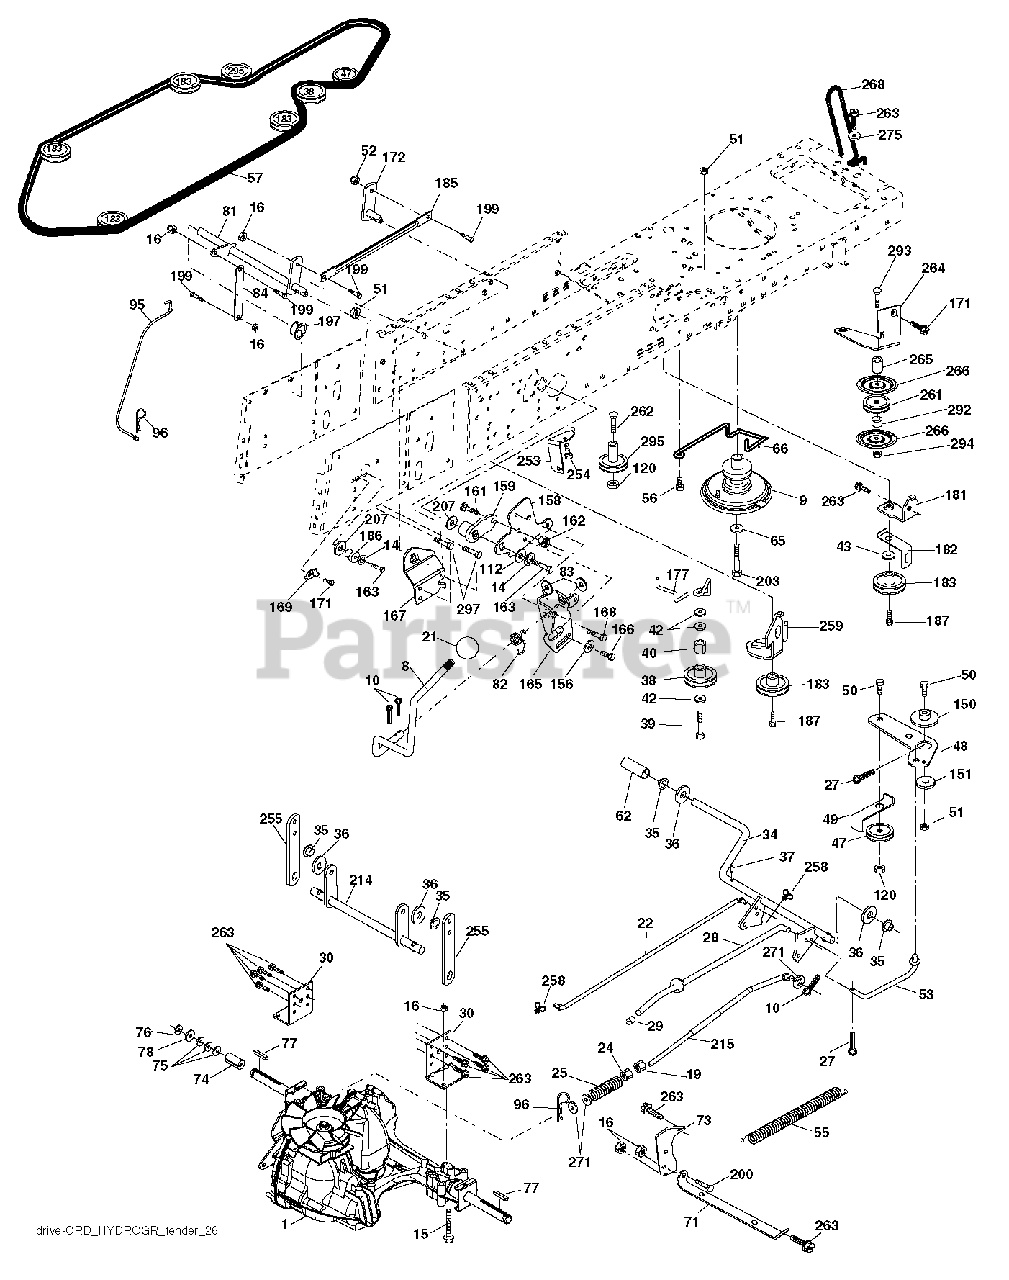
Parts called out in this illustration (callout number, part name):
8	ROD SHIFT FENDER ADJUST LT
10	PIN COTTER
14	LOCKWASHER
15	BOLT HEX 5/16-18 GR 5
16	NUT.71038.31-18.HEX.NYLOCK
19	NUT
21	KNOB T (1/2-HOLE)
24	NUT
27	COTTER PIN
28	ROD, PARKING BRAKE
29	PLUNGER CAP
30	BRKT, TRNSXLE MNT 20"
34	SHAFT, FOOT PEDAL
35	BEARING.NYLON
36	WASHER LT
37	DRIVE PIN
38	PULLEY.FLAT
42	WASHER
47	IDLER PULLEY
48	BELLCRANK, CLUTCH
49	RETAIN BELT
50	BOLT.3/8-16X1.50
51	LOCKNUT
52	LOCKNUT
53	LINK.CLUTCH.7.66.2005
55	SPRING, RETURN LT
56	SCREW.3/8-16
62	PEDAL COVER T
65	LOCKWASHER
66	KEEPER BELT ENGINE
71	STRAP TORQUE LH HYDRO
73	STRAP TORQUE RH HYDRO
74	SPACER AXLE
76	E-RING LT
77	SQUARE KEY
81	SHAFT ASSY
82	SHIFT SPRING
83	WASHER
96	RETAINER M
112	WASHER LT
120	NUT LOCK FLG 3/8-16 UNC
150	BUSHING.BELLCRANK.GRD.DR
151	WASHER 12/32X2X10GA
156	WASHER.SRRTD.5/16
158	BRACKET.SHIFT.MOUNT
159	HUB.SHIFT
161	BOLT
162	NUT.CROWNLOCK.1/4
165	BRACKET.PIVOT.LEVER
167	BRACKET
168	BOLT.SHOULDER.5/16-18X
169	PLATE.FASTENING.CROSS.SHAFT
183	PULLEY.V-IDLER.
187	BOLT.5/16-18X1.25
197	NYLINER SNAP 5/8" ID
199	BOLT SHOULDER 5/16-18 UNC
200	BOLT
207	WASHER NYL
254	SCREW 3/8-16X1
258	CLIP RETAINER
261	FLAT IDLER PULLEY
263	SCREW, 3/8-16X3/4
271	WASHER
275	WASHER
294	NUT, HEX 3/8-16
295	PULLEY IDLER COMPOSITE
297	SCREW LT.3/8-46X5/8
